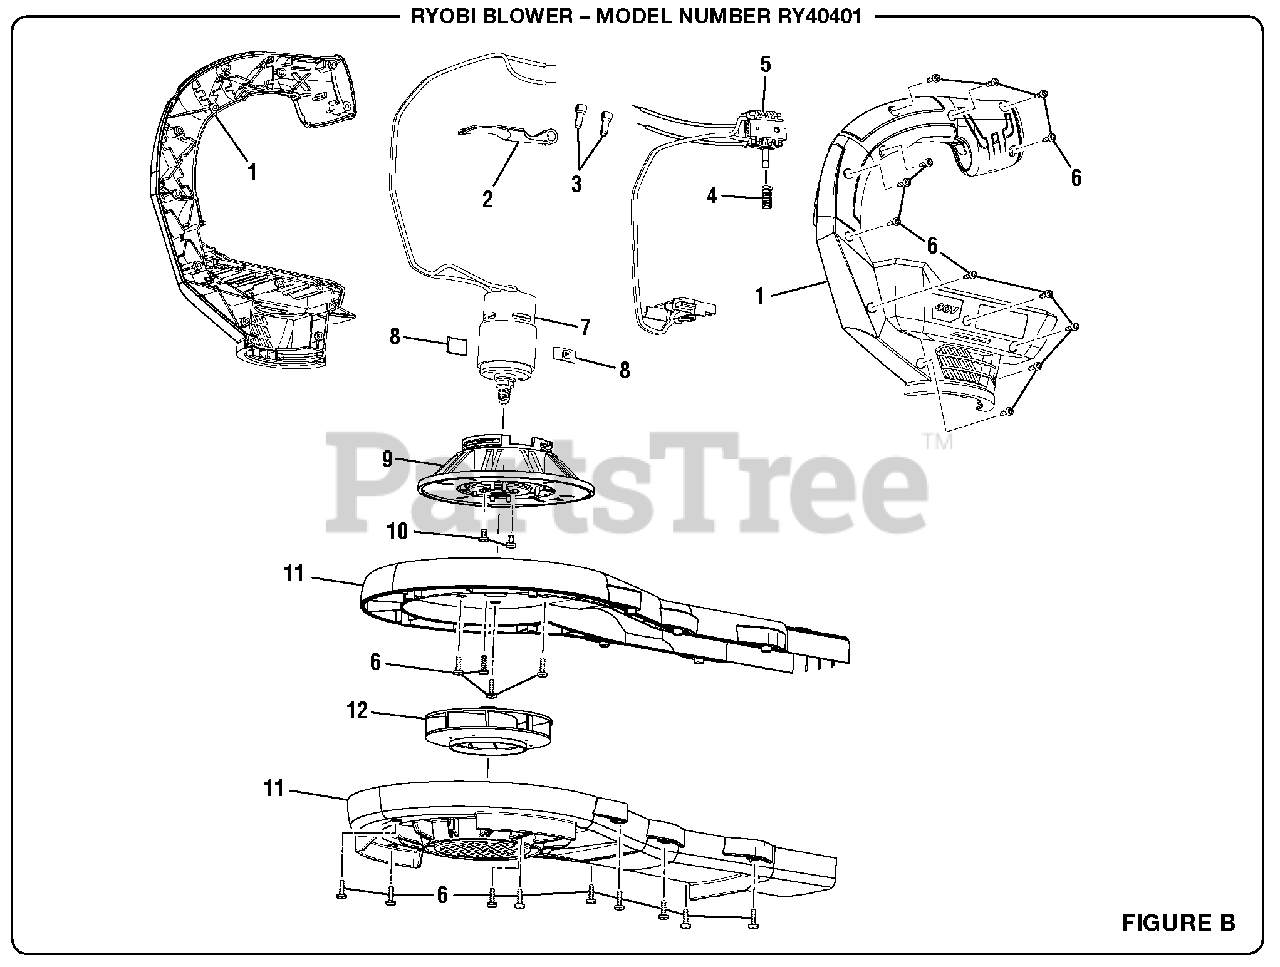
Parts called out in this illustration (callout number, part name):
1	Handle Assembly
2	Switch Trigger
3	Wire Connector
4	Compression Spring
5	Switch Assembly
6	Screw (M4 x 14 mm)
7	Motor Assembly
8	Rubber Pad
9	Motor Mount
10	Screw w/Washer (M4 x 10 mm)
11	Blower Housing Assembly
12	Impeller Assembly
